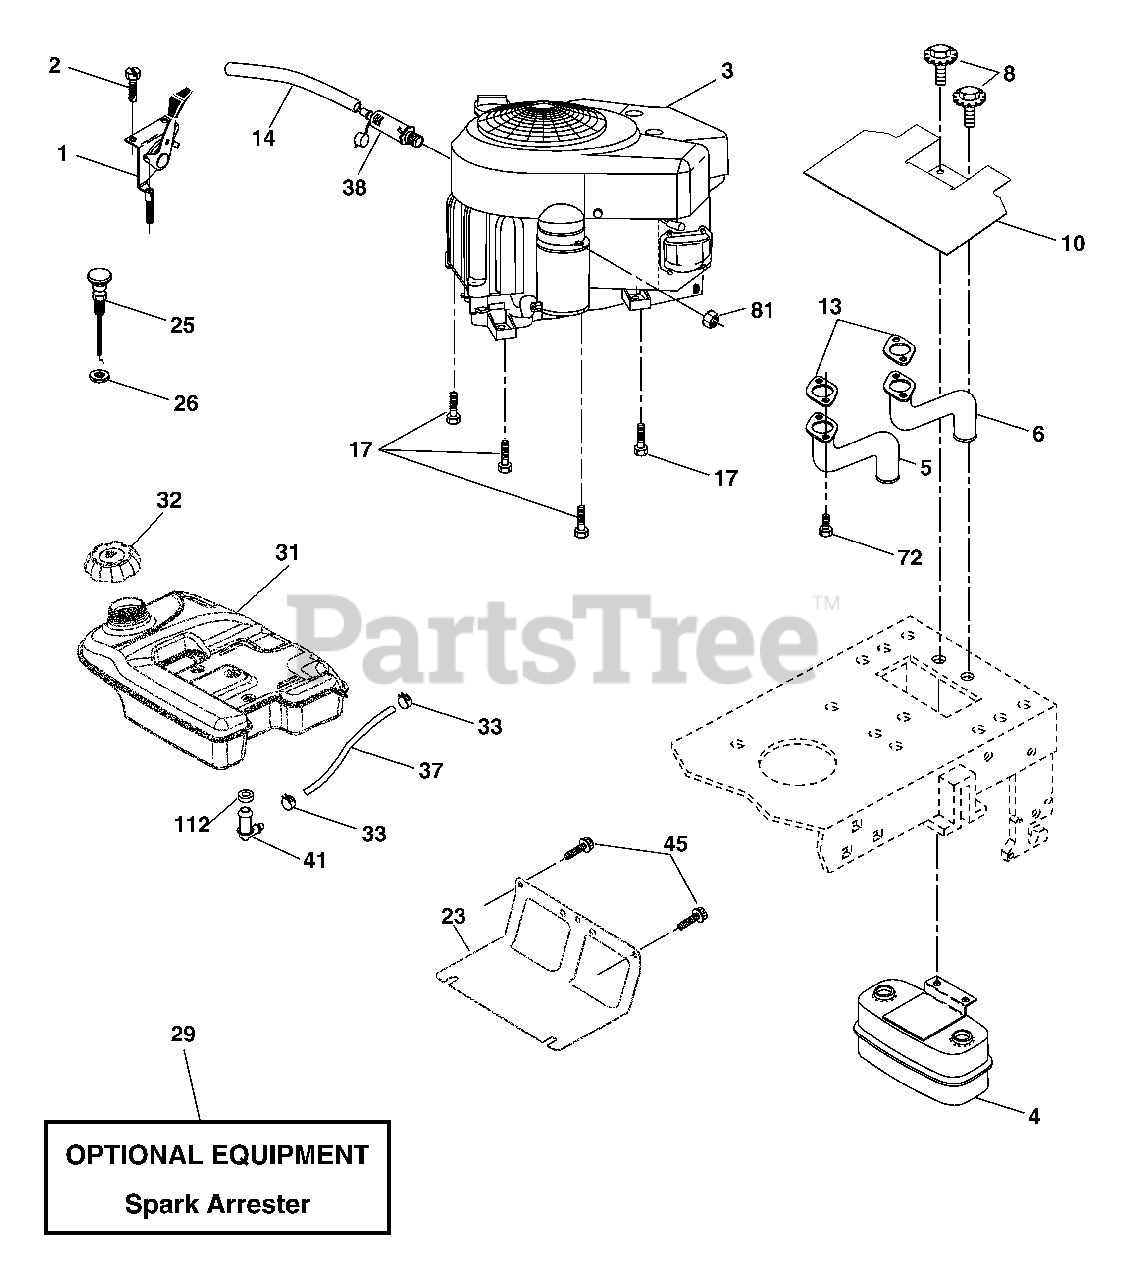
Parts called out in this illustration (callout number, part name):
1	Control Throttle
2	Screw Hex Thd Cut 1/4-20 x 1/2
5	Exhaust Tube LH
6	Exhaust Tube RH
8	Bolt 5/16-18 unc x 3/4
10	Shield Heat Muffler
14	Tube Drain Oil Easy
17	Screw 3/8-16 x 1-1/2
23	Shield Browning/Debris Guard
25	Control Choke
26	Nut Keps 3/8-24 unf
29	Kit Spark Arrestor (Flat Scrn)
32	Cap Asm Fuel
33	Clamp Hose Black
37	Line Fuel
38	Plug Drain Oil Easy
41	Stem Tank Fuel
45	Screw Hex Wsh Thdr 3/8-16 x 3/4
72	Screw Socket Head 5/16-18 x 1
81	Nut Keps Hex 1/4-20 Starter Nut
112	Bushing
